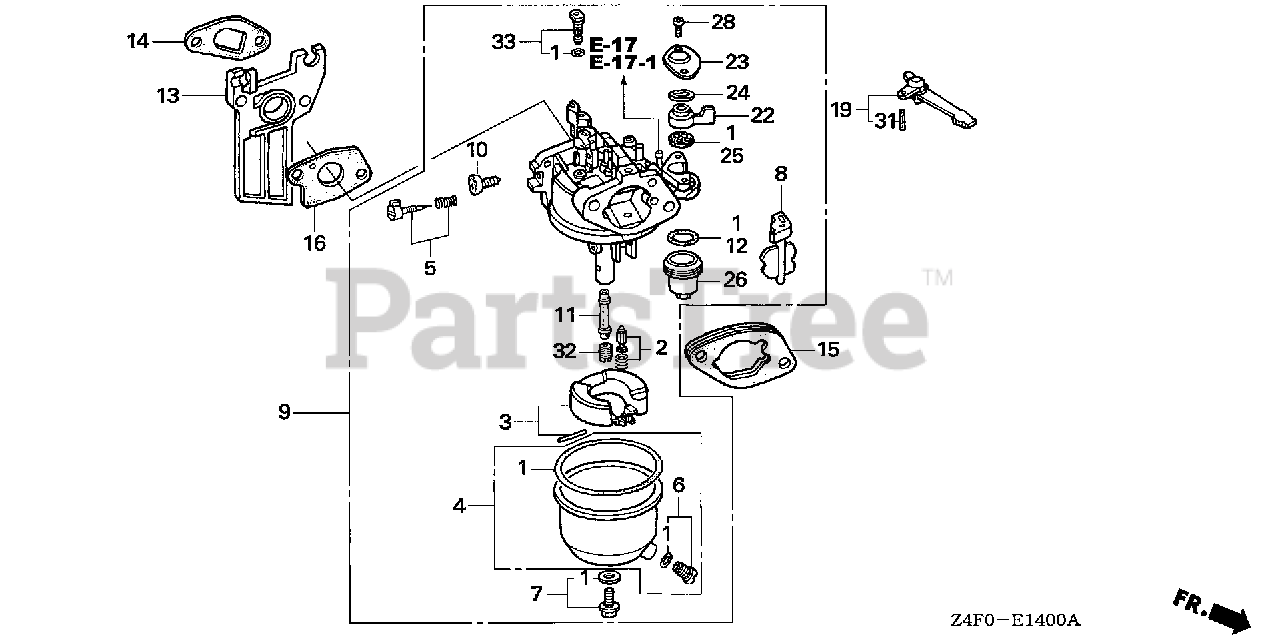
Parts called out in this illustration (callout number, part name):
1	GASKET SET
2	VALVE SET, FLOAT (SEAT NOT INCLUDED)
4	CHAMBER SET, FLOAT
5	SCREW SET, PILOT
6	SCREW SET, DRAIN
7	SCREW SET
9	CARBURETOR ASSY. (BE60F B)
10	SCREW, THROTTLE STOP
11	NOZZLE, MAIN
12	GASKET, FUEL STRAINER CUP
13	INSULATOR, CARBURETOR
14	GASKET, INSULATOR
15	SPACER, CARBURETOR
16	GASKET, CARBURETOR
19	LEVER, CHOKE (STD)
22	LEVER, PETCOCK
23	PLATE, LEVER SETTING
24	SPRING, PETCOCK LEVER
25	GASKET, PETCOCK
26	CUP, FUEL STRAINER
28	SCREW, PAN (3X6)
31	PIN, SPRING (2X12)
32	JET, MAIN (#58)
32	JET, MAIN (#60)
32	JET, MAIN (#62)
33	JET SET, PILOT (#38)
